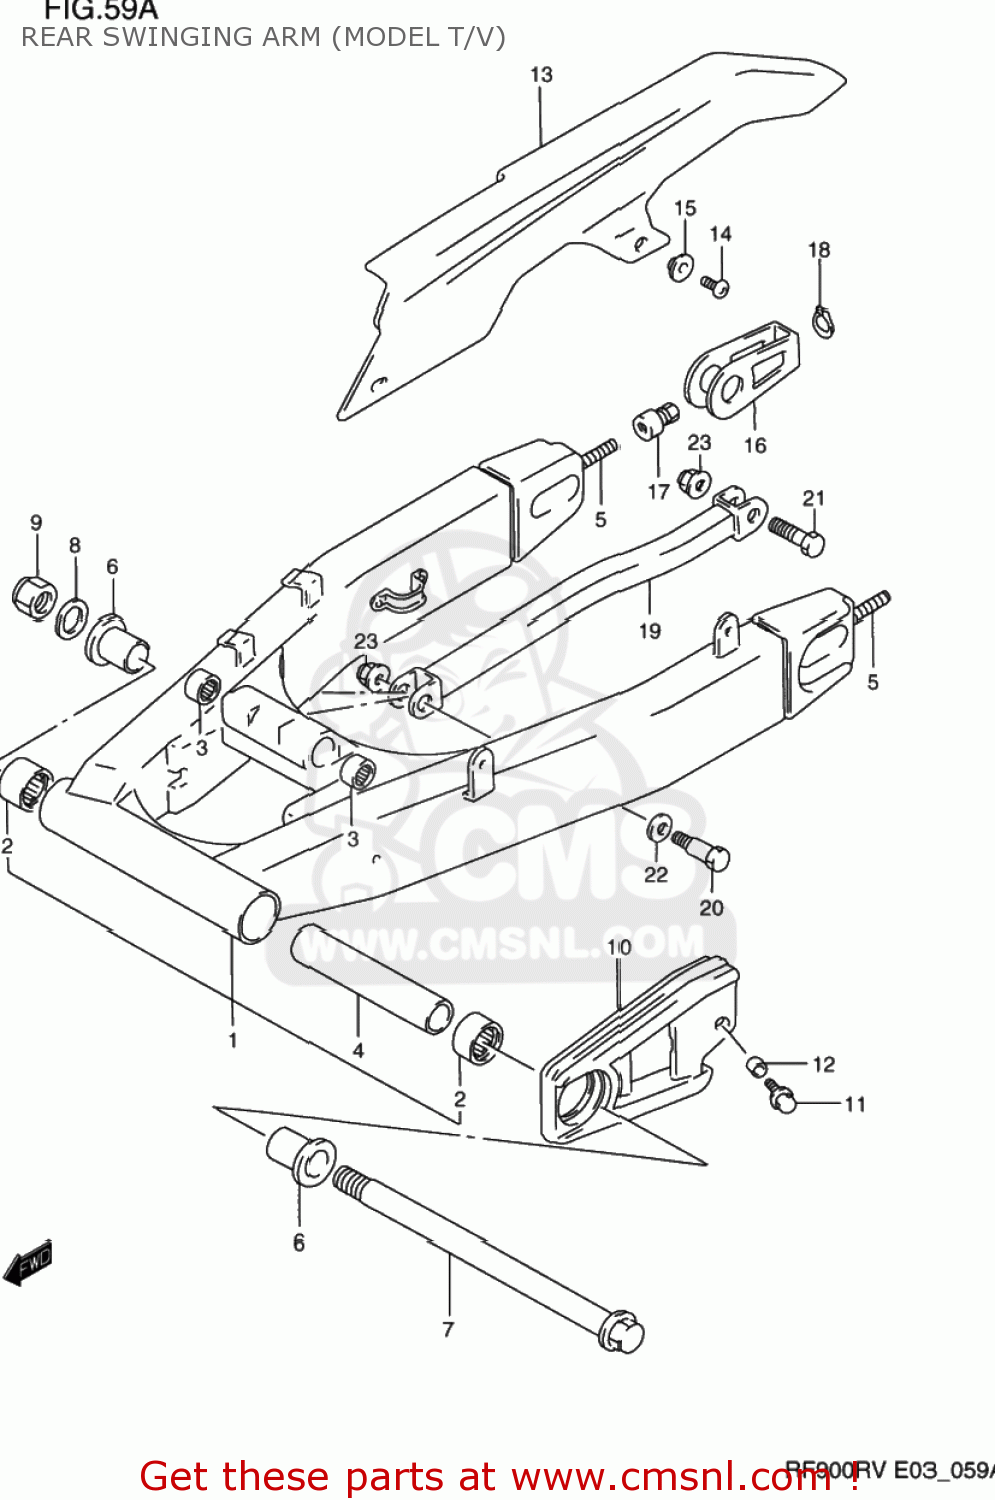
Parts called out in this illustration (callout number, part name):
1	SWINGINGARM ASSY,RR
2	BEARING(25X33X35)
3	BEARING(17X24X25)
4	SPACER,RR SWGARM PIVOT CTR
5	STUD,CHAIN ADJUSTER BOLT
6	SPACER,RR SWGARM PIVOT BERRING
7	SHAFT,RR SWINGINGARM PIVOT
8	WASHER(18.5X28X2.6)
9	NUT
10	BUFFER,CHAIN TOUCH DEFENSE
11	BOLT 6X20,WITH PLAIN WASHER
12	SPACER(6.5X10X7)
13	CASE,CHAIN
14	SCREW 6X12
15	WASHER
16	ADJUSTER,CHAIN
17	NUT,CHAIN ADJUSTER
18	CIRCLIP
19	TORQUELINK,RR
20	BOLT(10X39)
21	BOLT(10X34)
22	WASHER(12.5X20X1)
23	NUT
